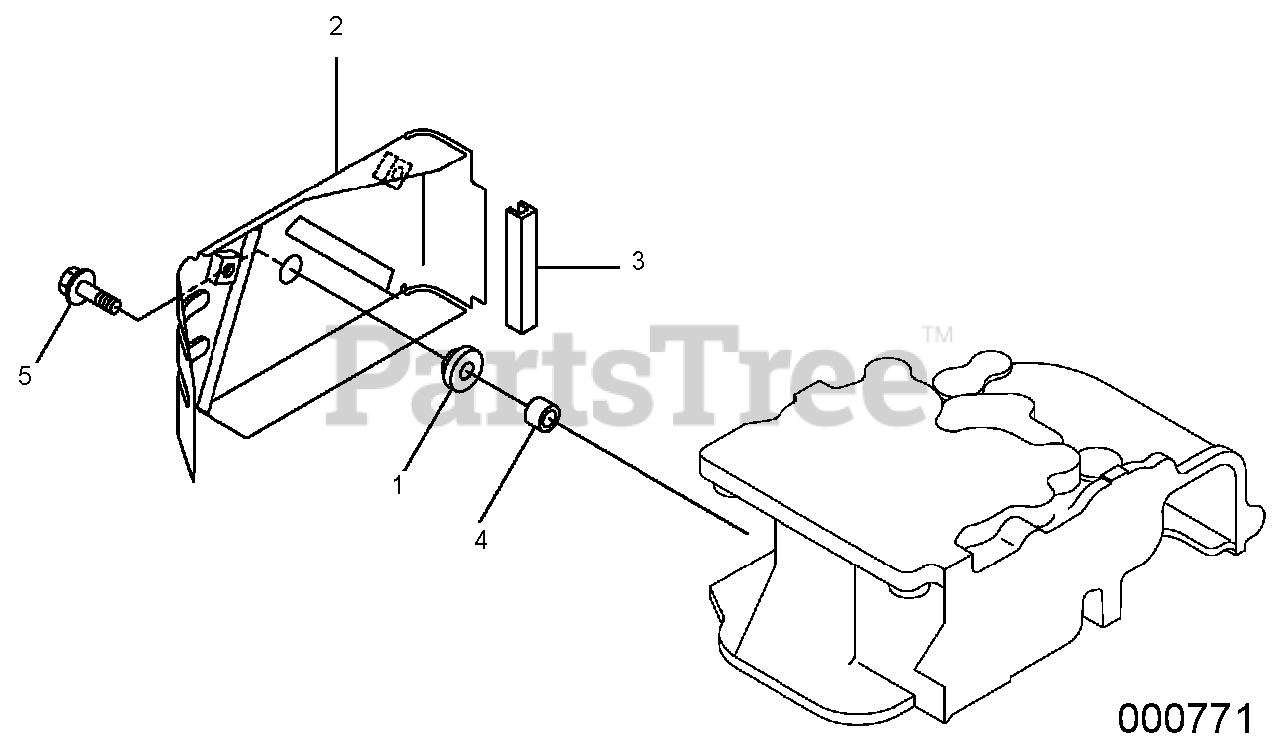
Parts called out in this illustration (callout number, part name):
2	SIDE COVER B
3	RUBBER SEAL
5	PLATED BOLT (M6X20)
